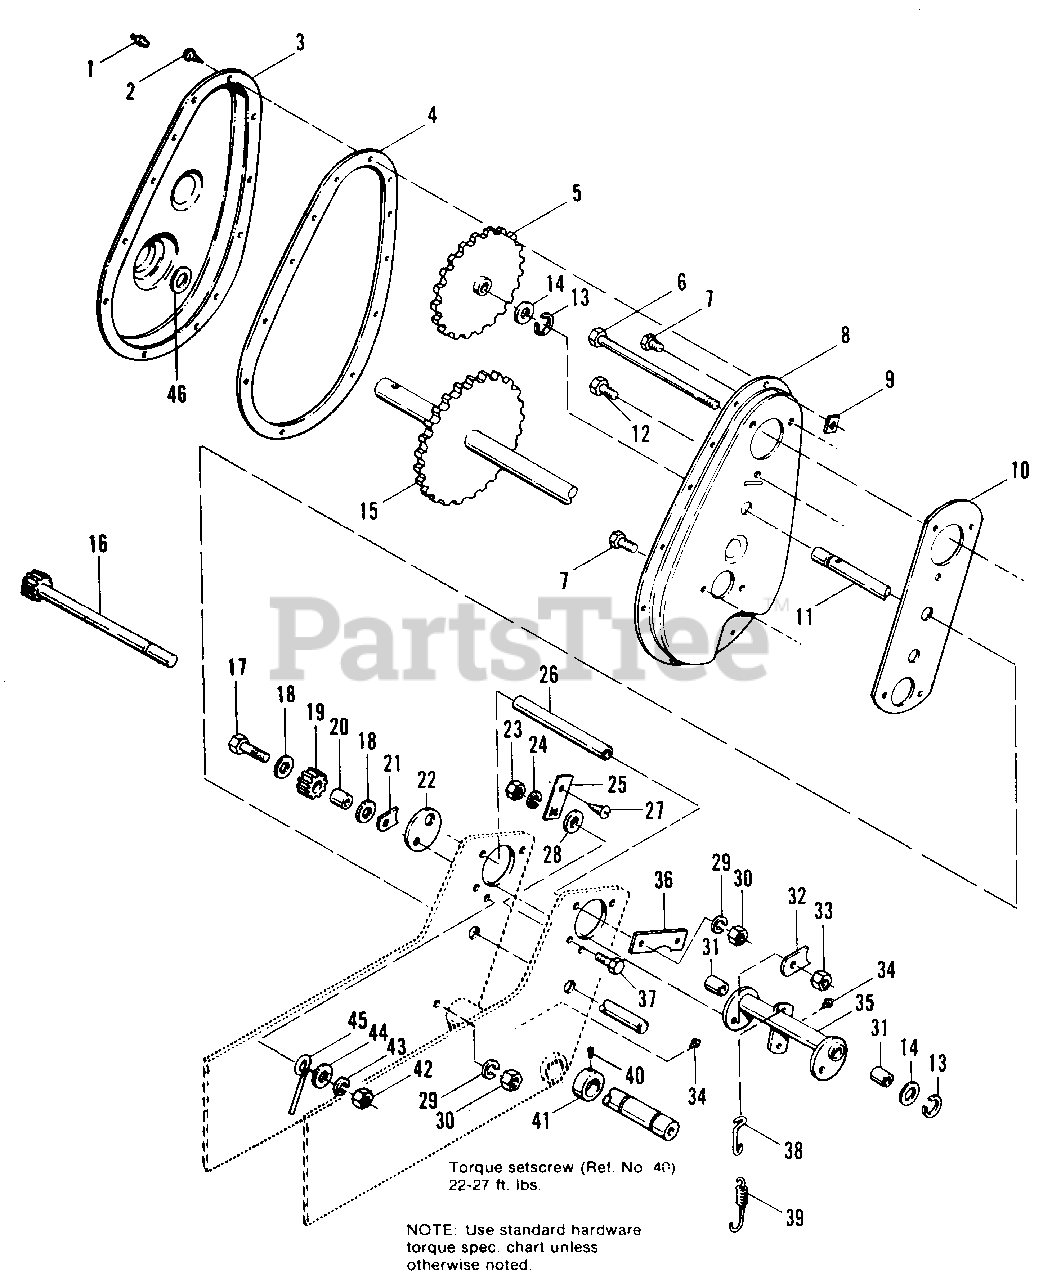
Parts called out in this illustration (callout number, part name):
1	FITTING, Grease, 7/16
2	SCREW, Self Tapping, #10 X 3/8
3	COVER ASSY., Gear Case
5	GEAR ASSY.
6	BOLT, Frame
7	CAPSCREW, Hex Hd., 5/16-18 x 5/8
8	CASE, Gear
9	NUT, Speed
11	SHAFT, Intermediate
12	CAPSCREW, Hex Hd., 3/8-16 x 1
13	RING, Retaining
15	AXLE & GEAR ASSY.
16	SHAFT ASSY., Pulley
17	CAPSCREW, Hex Hd., 3/8-16 x 1-1/2
18	WASHER, Plain, 5/16
20	SPACER, Pinion
21	SPACER, Reverse Pinion
23	NUT, Hex, Full, 1/4-20
24	LOCKWASHER, 1/4
25	NUT, Speed
26	SPACER, Frame
27	SCREW, Self Tapping, #10 x 3/8
28	WASHER, Plain, 1/4
29	LOCKWASHER, 5/16
30	NUT, Hex, Full, 5/16-18
32	PLATE, Lock
33	NUT, Hex, Full, L.H. Thd., 3/8-16
34	FITTING, Grease (1690378 Only)
34	FITTING, Grease
35	HOUSING, W/Bearings (Includes Ref. Nos. 31 & 34)
36	PLATE, Friction Stop
37	CAPSCREW, Hex Hd., 1/4-20 x 5/8
38	SPRING, Extension
39	SPRING, Reverse Lever
40	SETSCREW, 5/16-18 x 1/2
41	COLLAR, Set
42	NUT, Hex, Full, 3/8-16
43	LOCKWASHER, 3/8
44	WASHER, Plain, 3/8
45	PIN, Lock
46	RING, Retaining
